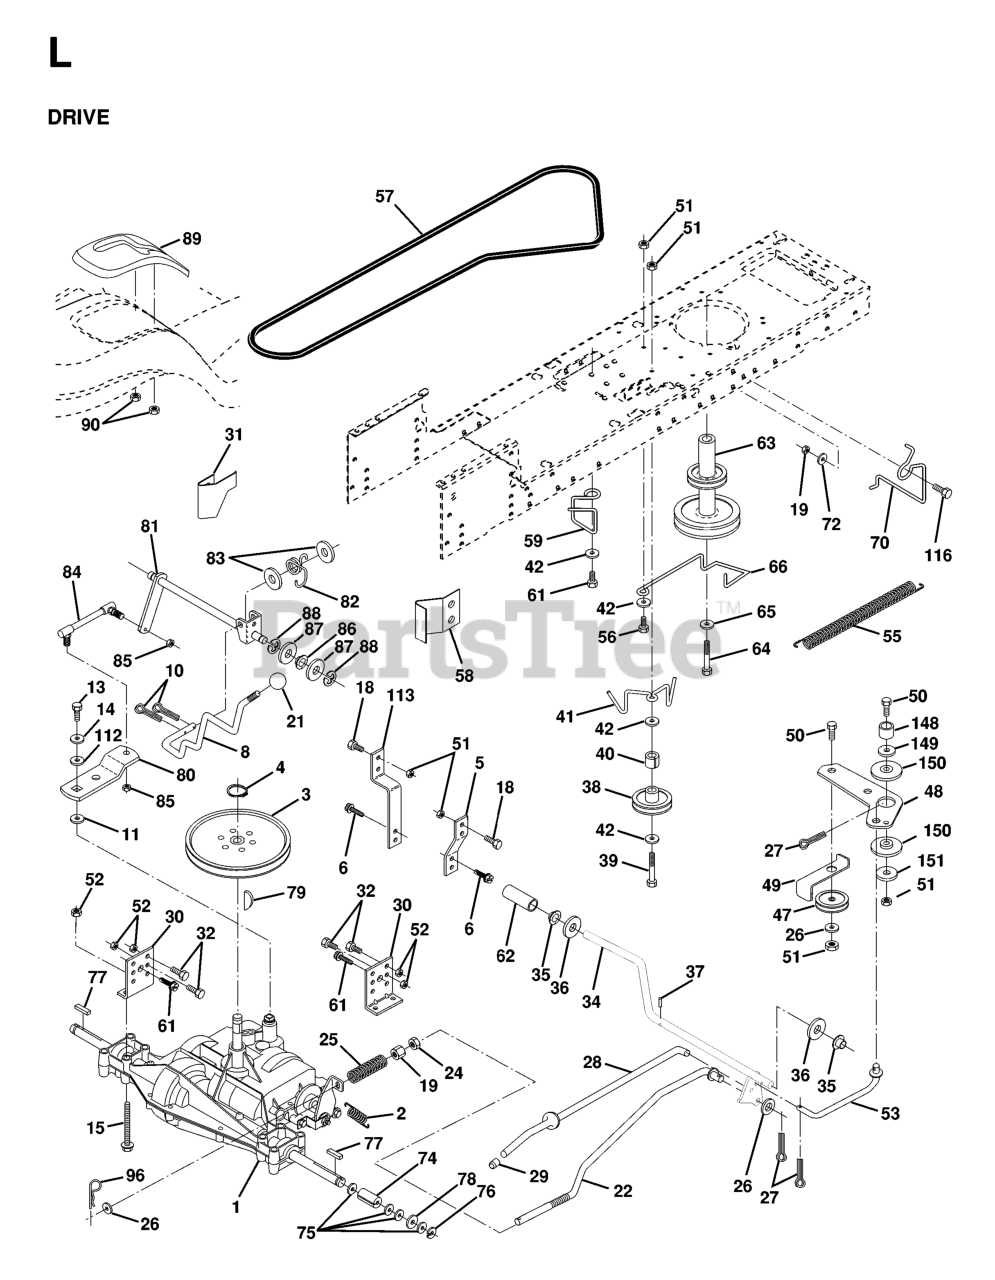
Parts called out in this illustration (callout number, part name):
2	SPRING,BRAKE RETURN
3	PULLEY TRANS
4	RETAINING RING LT
5	STRAP TORQUE
6	SCREW.THDROL.5/16-18X3/4.TTY
8	ROD SHIFT FENDER
10	PIN COTTER
11	WASH-SHFT PLT LT
13	BOLT 1/4-28X3/4
14	LOCKWASHER
15	BOLT HEX 5/16-18 GR 5
19	NUT
21	KNOB.DUCKHEAD.1/2
24	NUT
25	SPRING ROD LT
26	WASHER
27	COTTER PIN
28	ROD BRAKE PARK LT
29	PLUNGER CAP
30	BRACKET TRANSAXLE
31	KEEPER BELT LH
32	BOLT
34	SHAFT, FOOT PEDAL
35	BEARING.NYLON
37	DRIVE PIN
38	PULLEY.IDLER.FLAT
41	KEEPER, BELT IDLER
42	WASHER
47	IDLER PULLEY
48	BELLCRANK, CLUTCH
49	RETAIN BELT
50	BOLT
52	LOCKNUT
53	LINK, CLUTCH LT
55	SPRING, RETURN LT
59	KEEPER CENTER SPAN
61	SCREW
62	COVER, PEDAL (1 2)
63	PULLEY.ENG.CL.MECH.SLVR.LT/YT
64	BOLT
65	LOCKWASHER
66	KEEPER BELT ENGINE
70	KEEPER BELT ENG
72	WASHER
74	SPACER AXLE
77	SQUARE KEY
79	KEY STD (1373) DANA
82	SPRING,TORSION
83	WASHER
84	ROD TIE 20"
85	NUT LOCK CENTER 1/4 -28 FNTHD
89	SHIFT CONSOLE
90	NUT.PUSH.3/16
96	RETAINER M
113	STRAP TORQUE LH LT
116	BOLT
149	SPACER RETAINER
150	BUSHING NYLON COLLERED
151	WASHER 12/32X2X10GA
